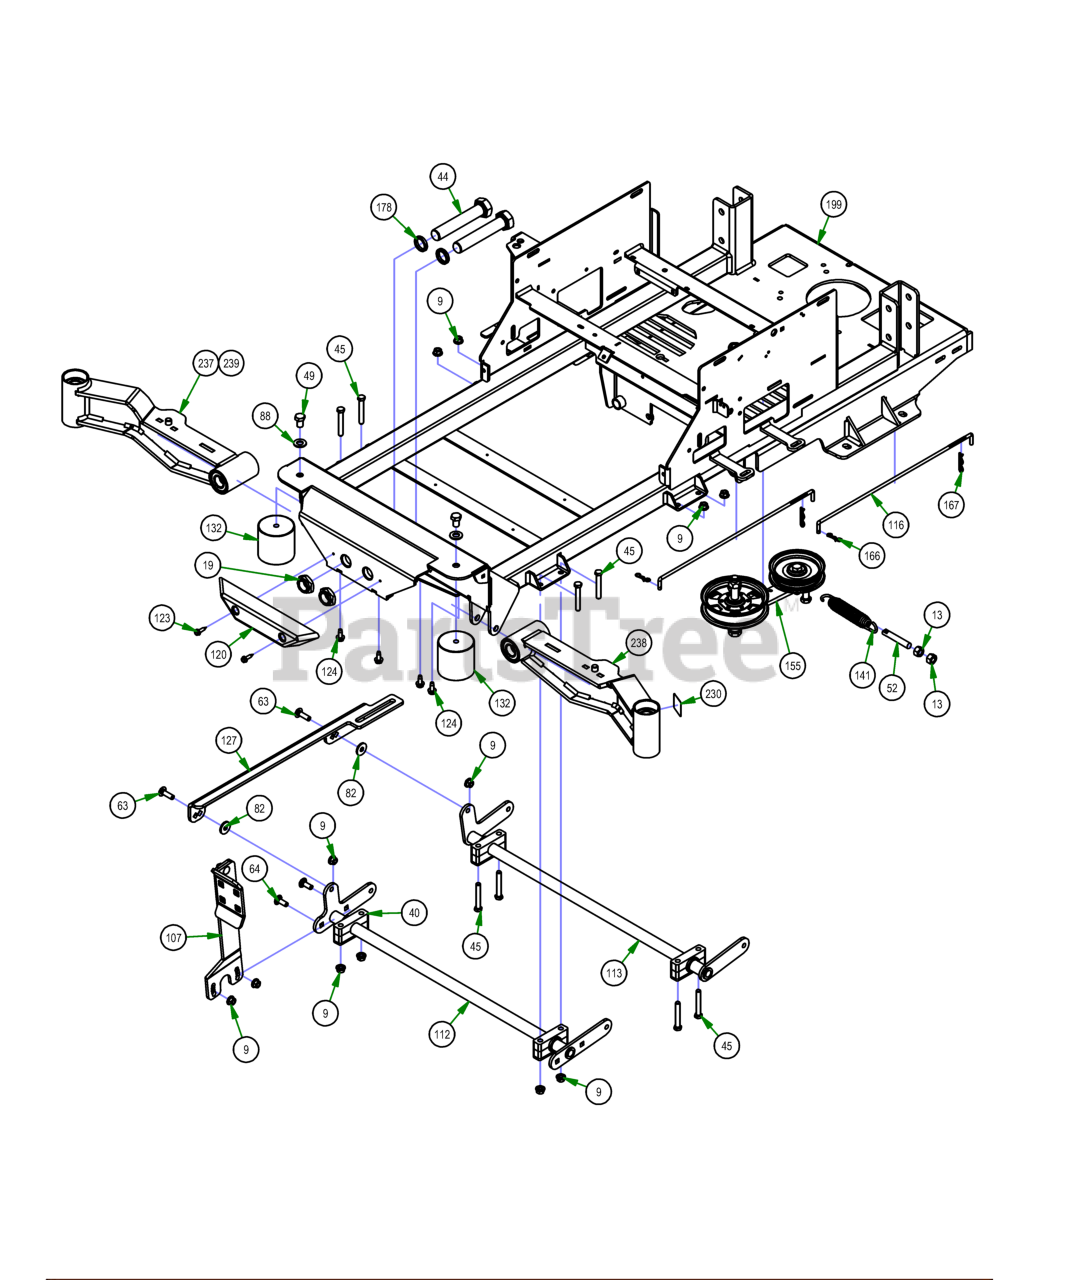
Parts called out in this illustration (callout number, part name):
9	3/8-16 NYLON INSERT FLANGE LOCKNUT (GR.F) ZINC
13	1/2-13 HEX NUT ZINC
19	1"-14 NYLON INSERT JAM LOCKNUT ZINC
40	Pillow Block Kit
44	1"-14 X 5-1/2 HEX CAP SCREW (GR.8) ZINC YELLOW
45	3/8-16 X 2-1/2 HEX CAP SCREW (GR.5) ZINC
49	1/2-13 X 3/4 HEX CAP SCREW (GR.5) ZINC
52	All Thread
63	3/8-16 X 1-1/4 CARRIAGE BOLT ZINC
64	3/8-16 X 1 CARRIAGE BOLT (GR.5) ZINC
82	.390 ID X 1.12 OD X .125 THK FLAT WASHER NYLON
88	1/2 SAE FLAT WASHER (1-1/16" OD) GR.8 ZINC YELLOW
107	Foot Pedal Assembly
112	Actuator Bar Front- 2017 MZ/ZT
113	Actuator Bar Rear- 2017 MZ/ZT
116	Neutral Rod
120	Bumper EZT
123	1/4 x 1 Hex Head Tek Screw
124	5/16-18 X 3/4 HEX WASHER SLOT (F) TCS ZINC
127	2017 MZ/ZT Actuator Linkage
132	Vibration Mount- Red Dot
141	Deck Idler Spring
155	Maverick Pump Idler
167	Neutral Rod Clip
178	Spacer, 1x1.375x.25
199	2021 Maverick Frame - Painted
213	Patent Decal
230	Independetly Articulating Front Suspension Arms Patent Decal
237	2021 Maverick RH Short Front Suspension Arm Assy (48")
238	2021 Maverick LH Front Suspension Arm Assy (48", 54" & 60")
